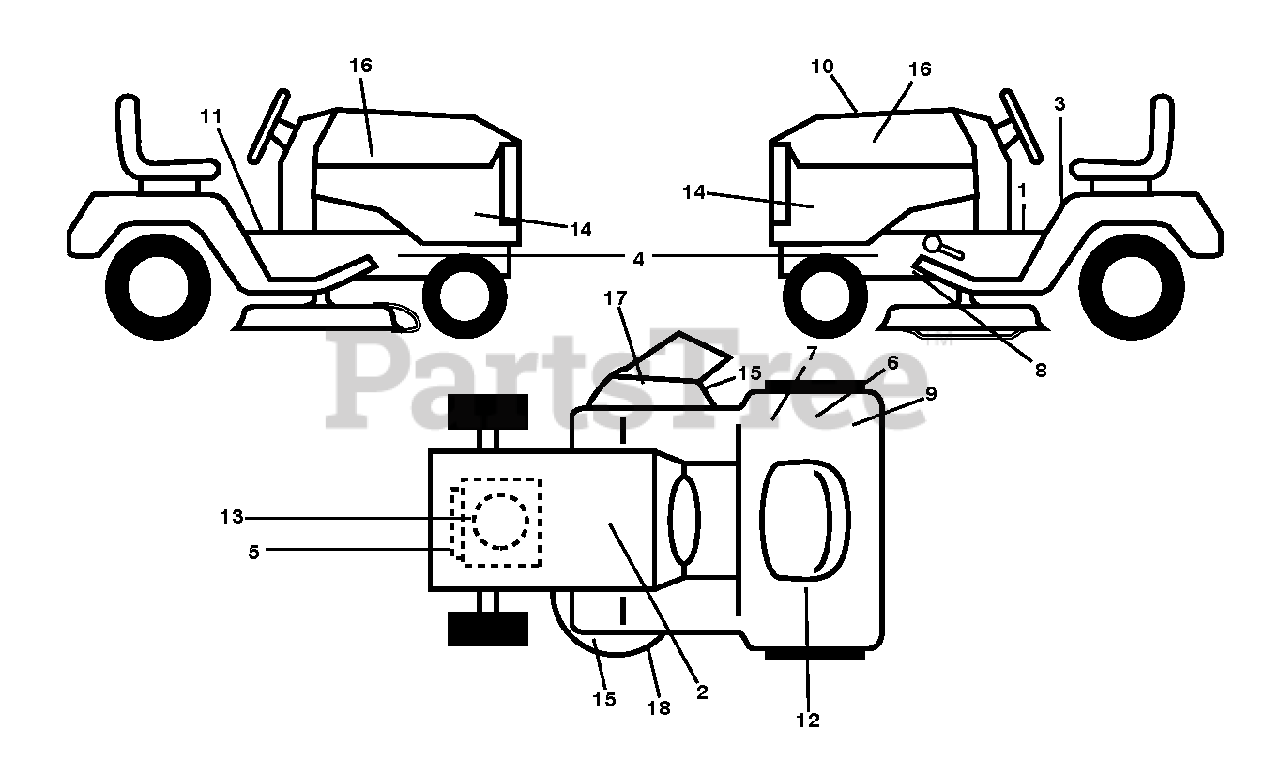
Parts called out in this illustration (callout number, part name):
1	DECAL PARK BRAKE
2	DECAL BTRY SYMBOLS
3	LABEL
5	DECAL, ENG. HP
6	DECAL
7	DECAL 80 DBA
8	DECAL.PEDAL.HUSQ.CROWN
9	DECAL
11	DECAL
12	DECAL.WARN.RESERVE.FUEL
13	DECAL
15	DECAL, CAUTION
16	RP.DECAL.BADGE.170MM.TEXTLOGO
17	DECAL, NO STEP
18	DECAL V BELT SCHEMATIC
